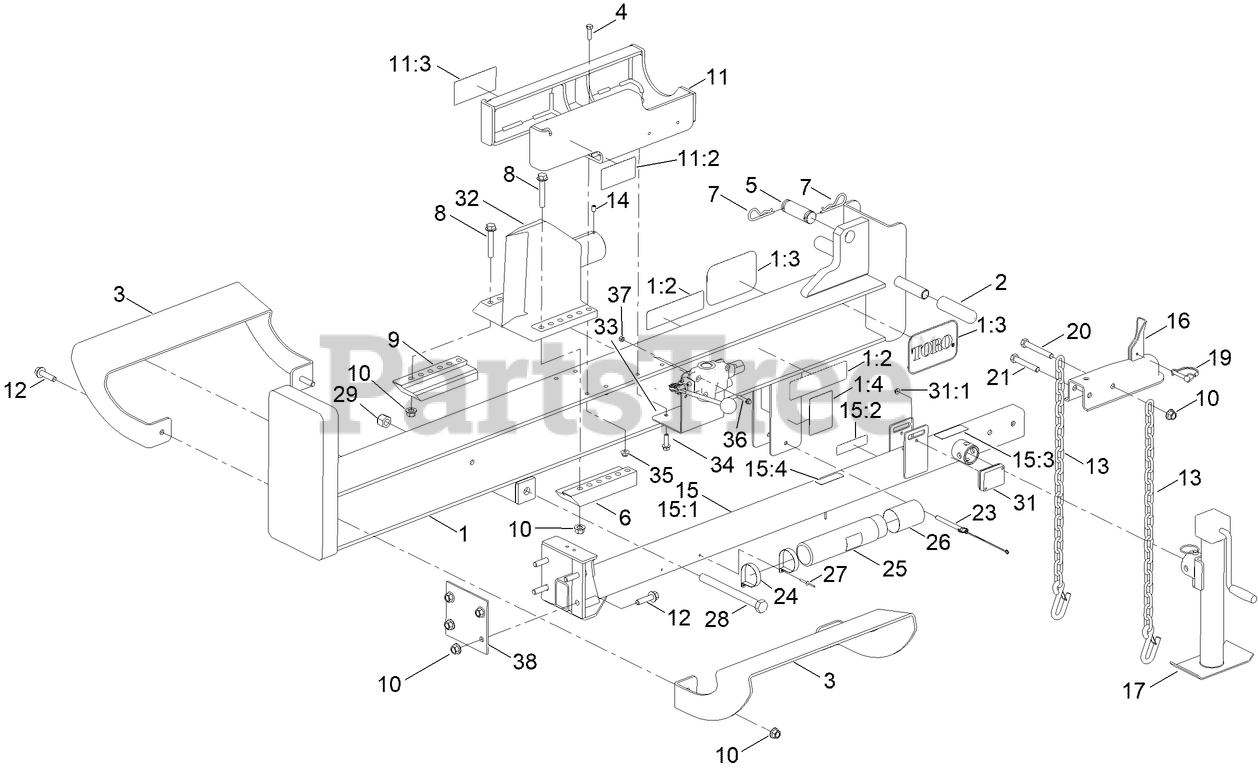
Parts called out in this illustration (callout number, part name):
1	BEAM ASM
1:3	DECAL
1:4	DECAL-WARNING, PIN
2	GRIP-HANDLE
3	PLATE-CATCH
4	SCREW-HH
5	PIN-PIVOT
6	BAR-SLIDE, LH
7	PIN-HAIR
8	SCREW-HF
9	BAR-SLIDE, RH
10	NUT-LOCK
11	DISLODGE BRACKET W/DECALS
11:2	DECAL-WARNING, PINCH POINT
11:3	DECAL-CAUTION, DANGEROUS AREA
12	SCREW-HF
13	CHAIN-SAFETY, TRAILER
14	SCREW-SET
15	DECAL ASM-TUBE
15:1	TONGUE ASM [RED]
15:2	DECAL-ARRESTOR, SPARK
15:3	DECAL-CAUTION
15:4	DECAL-WARNING, PINCH POINT
16	RECEIVER-BALL HITCH
19	PIN-LOCK
20	SCREW-HH
21	SCREW-HH
24	CLAMP-R
25	TUBE-MANUAL
26	CAP-HOUSING
27	RIVET-BLIND
28	BOLT-HH
29	NUT-LOCK, NI
31	LAMP-MARKER, FRONT SIDE
31:1	NUT-KEPS
32	WEDGE [BLACK]
33	BRACKET-VALVE
34	SCREW-HHF
35	NUT-HF, NI
36	SCREW-HHF
37	NUT-LOCK, NI
38	PLATE - BACKING
